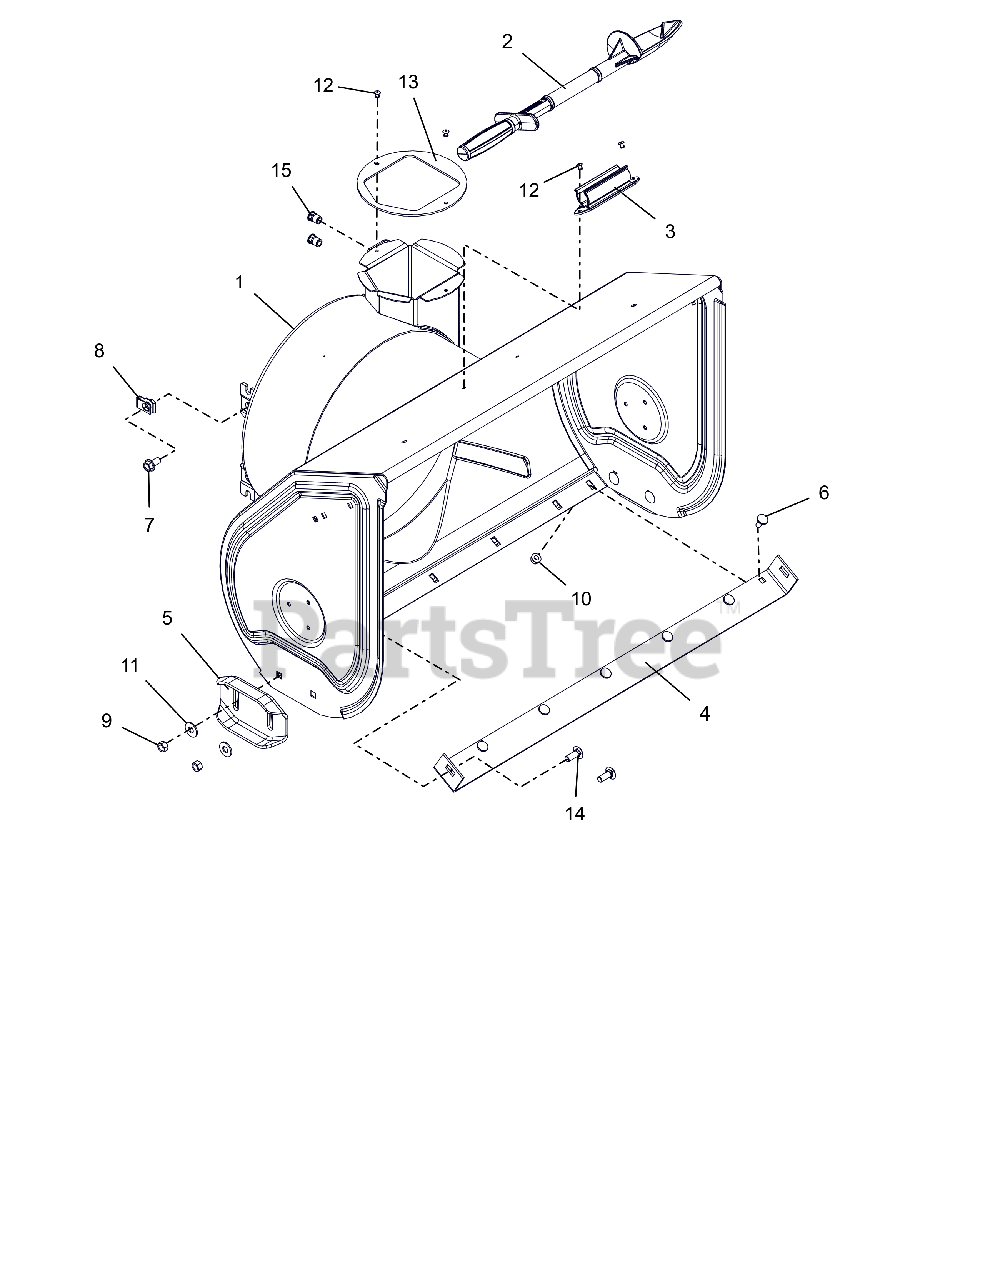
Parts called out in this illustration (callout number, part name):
1	BLOWER HOUSING W/DECAL 30"
2	DEVICE, SNOW CLEAN OUT
3	MOUNT, SNOW CLEAN OUT
4	BLADE, SCRAPER-30"
5	SKID SHOE, REVERSIBLE - ORANGE
6	BOLT, MODIFIED HEAD CARRIAGE
7	BLT-SERHFWH .38-16X.75 YWZC
8	NUT-RTNR .375-16X.37
9	NUT-LK-CTR .38-16 ZC120
10	NUT-LK-TOP-FLG .312-18 GF ZCC
11	WSHR,FLT .438X1.00X.083 ZCC
12	RVT-POP .187 YZ
13	BAFFLE, DISCHARGE NECK
14	BLT,RHSSN .38-16X1.00 G5 ZCC
15	NUT, THREADED INSERT .38-16
